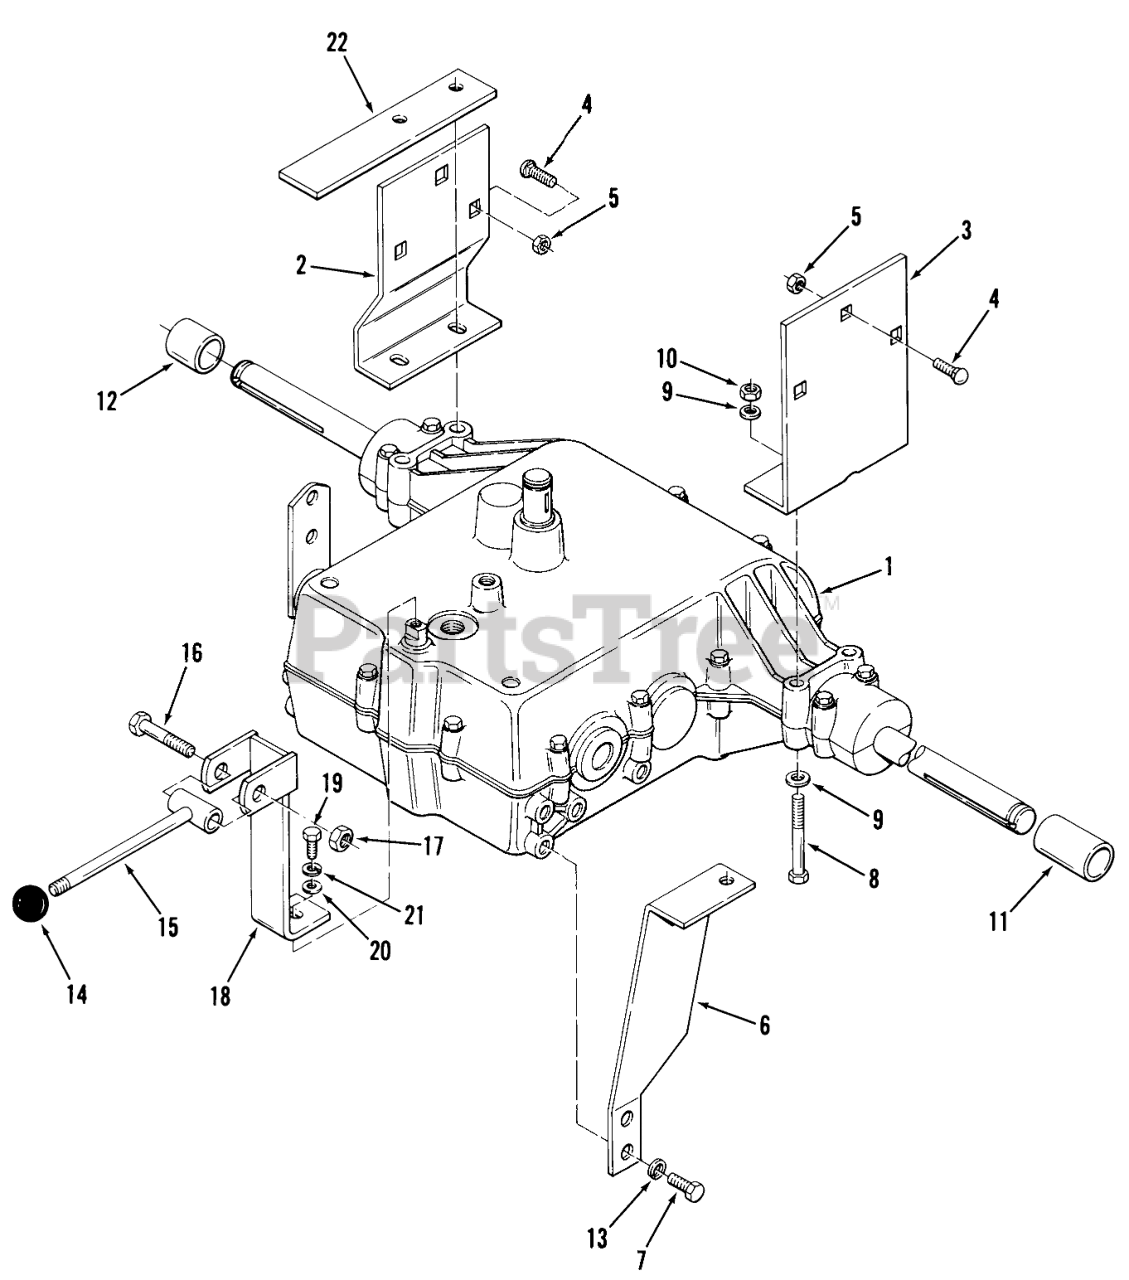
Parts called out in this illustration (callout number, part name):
1	Transmission-Peerless Model 812
2	Bracket-Rear Axle RH
3	BRK-TRANS MTG LH
4	CARRIAGE BOLT -4
5	Nut
6	Torque Strap
7	Screw
8	HHCS
9	WASHER 5/16 SAE
10	Nut
11	Axle Spacer LH
12	SPACER-AXLE RH
13	Lockwasher
14	SHIFT KNOB
15	ASSY-UP SHIFT ROD
16	Bolt
17	Nut
18	Shift Lever-Lower
19	Bolt 1/4-28 X 7/8
20	WASHER
21	Washer
22	Brake Stop Bar
